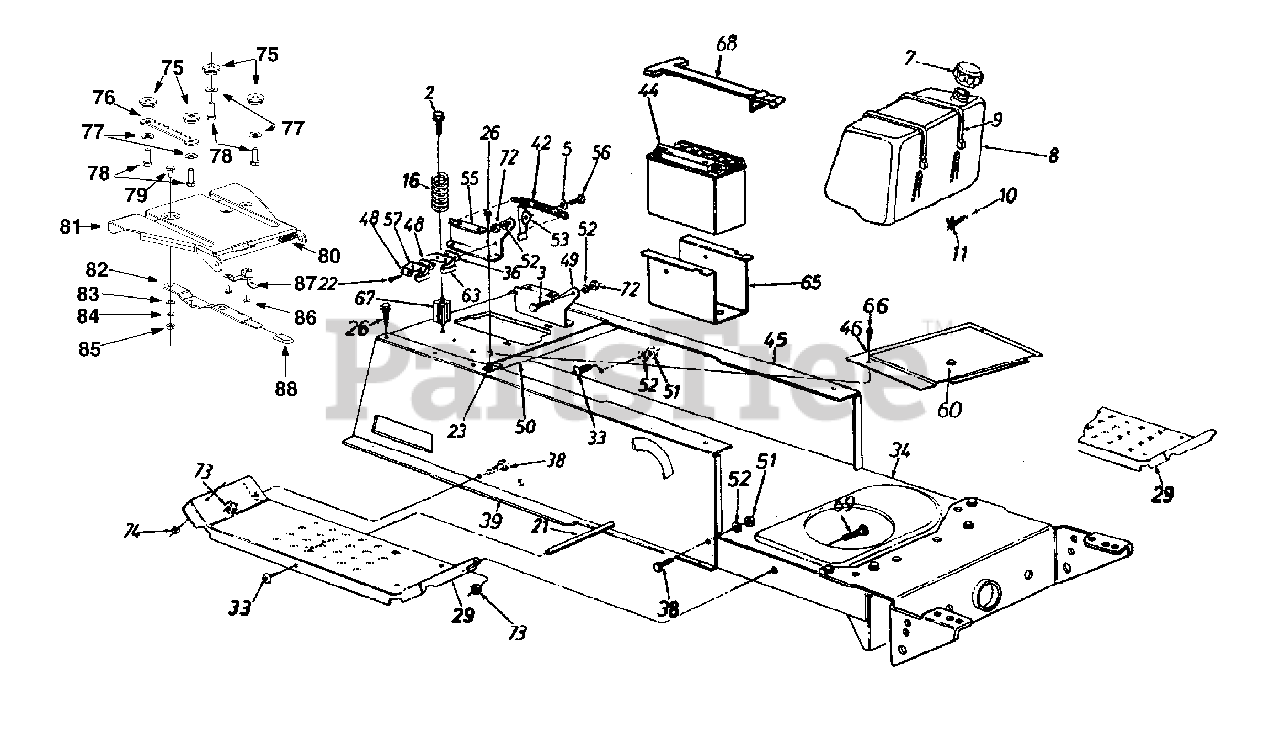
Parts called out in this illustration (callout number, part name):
2	Hex Wash. Hd. Tap Scr.5/16-18 x 3.25" Lg.
3	Shld. Bolt .437" Dia. x .162"
5	Spr-Wash. .445" I.D. x .75
7	Fuel Cap
8	Fuel Tank
9	Tie Strap
10	Fuel Line
11	Hose Clamp
13	Hex Nut 1/4-20 Thd.
16	Compression Spring
21	Running Board Rod
22	Hex Wash. Hd. AB-Tap Scr.#8 x .50" Lg.
23	Speed Nut #10Z
26	Hex Wash. Hd. AB-Tap Scr.5/16 x .75" Lg.
36	Insulator Boss Plate
38	Hex Bolt 5/16-18 x .75" Lg.
39	Upper Frame-R.H.
42	Extension Spring 5.31" Lg.
44	12-V Battery
45	Upper Frame-L.H.
52	L-Wash. 5/16" I.D.
53	Seat Lift Brkt.
56	Shld. Bolt .437" Dia. x .268"
57	Spring Switch (Seat)
60	Snap Bushing
63	Safety Switch (Seat)
66	Truss Mach. B-Tap Scr.#10 x .5" Lg.
67	Spring Spacer
68	Battery Retainer Strap
69	Hex Bolt 5/16-18 x .75" Lg.
72	Hex Nut 5/16-18 Thd.
73	Hex Sems Nut 5/16-18 Thd.
74	Hex Sems Nut 1/4-20 Thd.
75	Spacer
76	Seat Selector
77	Fl-Wash. .406" I.D. x .875" O.D.
78	Hex Bolt 3/8-16 x 1" Lg.
79	Shld. Bolt .34" x 1/4-20 Thd.
80	Compression Spring
83	Fl-Wash. .344" I.D. x .62" O.D.
84	Spring Wash. .265" I.D.
85	Hex Flanged L-Nut 1/4-20 Thd.
86	Hex Wash. Hd. B-Tap Scr. #10-16 x .38" Lg.
87	Seat Stop
88	Seat Adjustable Grip
